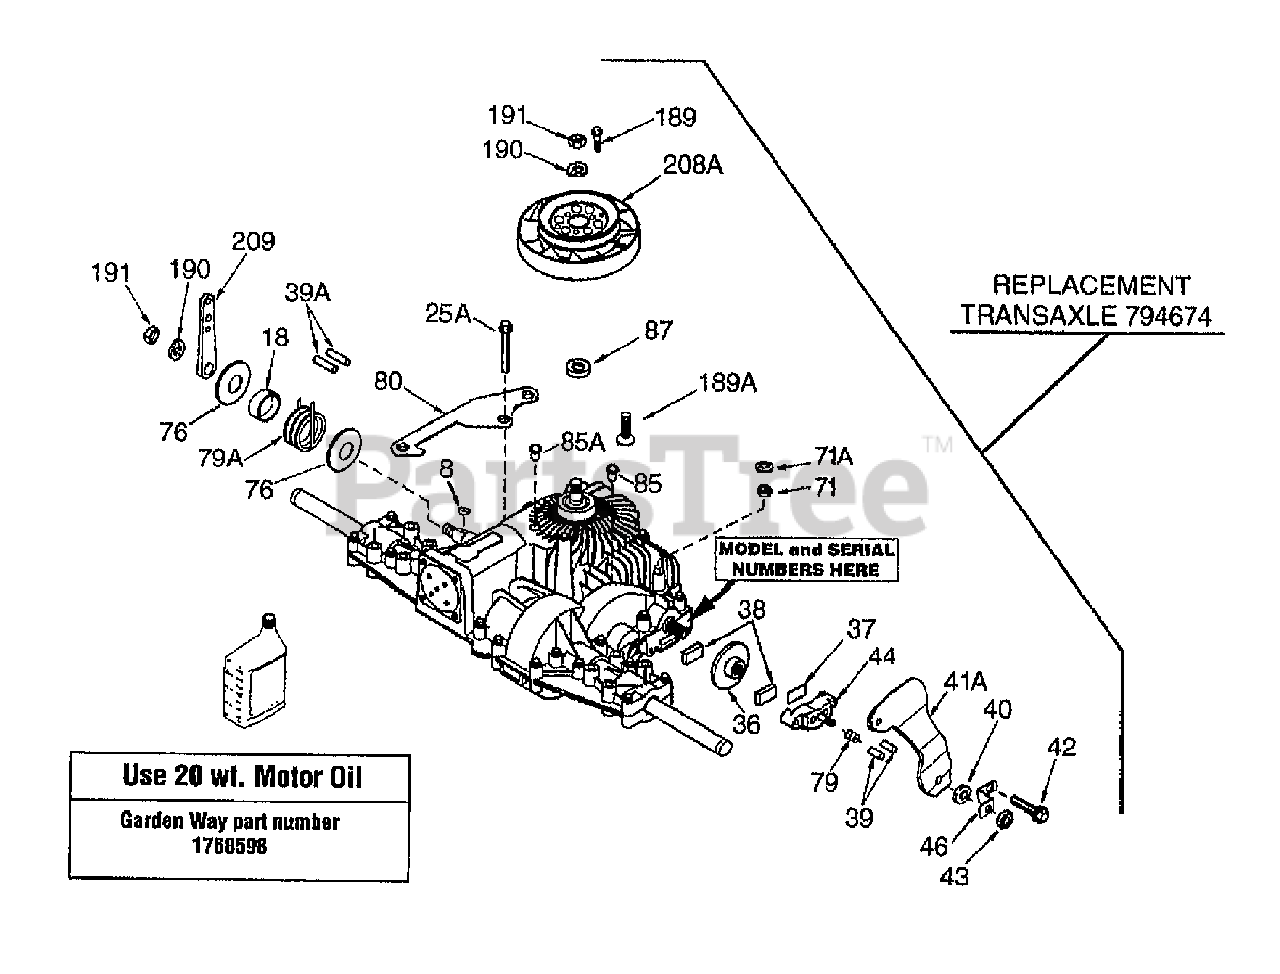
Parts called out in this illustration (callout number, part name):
8	WOODRUFF KEY
36	BRAKE DISK
37	BRAKE PAD PLATE
38	BRAKE PAD
39	DOWEL PIN
39A	DOWEL PIN
41A	BRAKE LEVER
80	CONTROL STOP
87	OIL SEAL
208A	FAN & COUPLING
209	CONTROL LEVER
